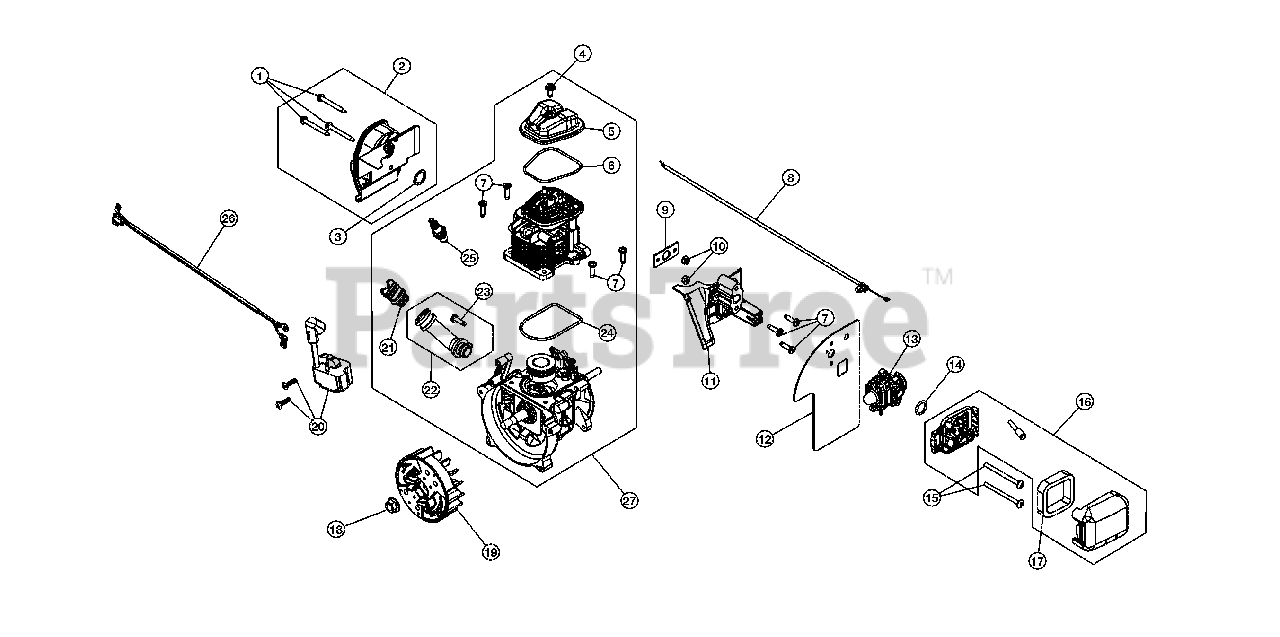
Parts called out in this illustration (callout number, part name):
1	Muffler Screws
2	Muffler Assembly (Incl. 1 & 3)
3	Muffler Gasket
5	Rocker Cover
7	Screw
8	Throttle Cable
9	Insulator Gasket
12	Carburetor Gasket
13	Carburetor
14	Carburetor O-Ring
16	Air Cleaner Assembly (Incl. 17)
19	Flywheel Asssembly
21	Oil Plug
22	Oil Fill Tube (Incl. 23)
25	Spark Plug
27	Short Block Assembly (Incl. 4-7 & 21-25)
